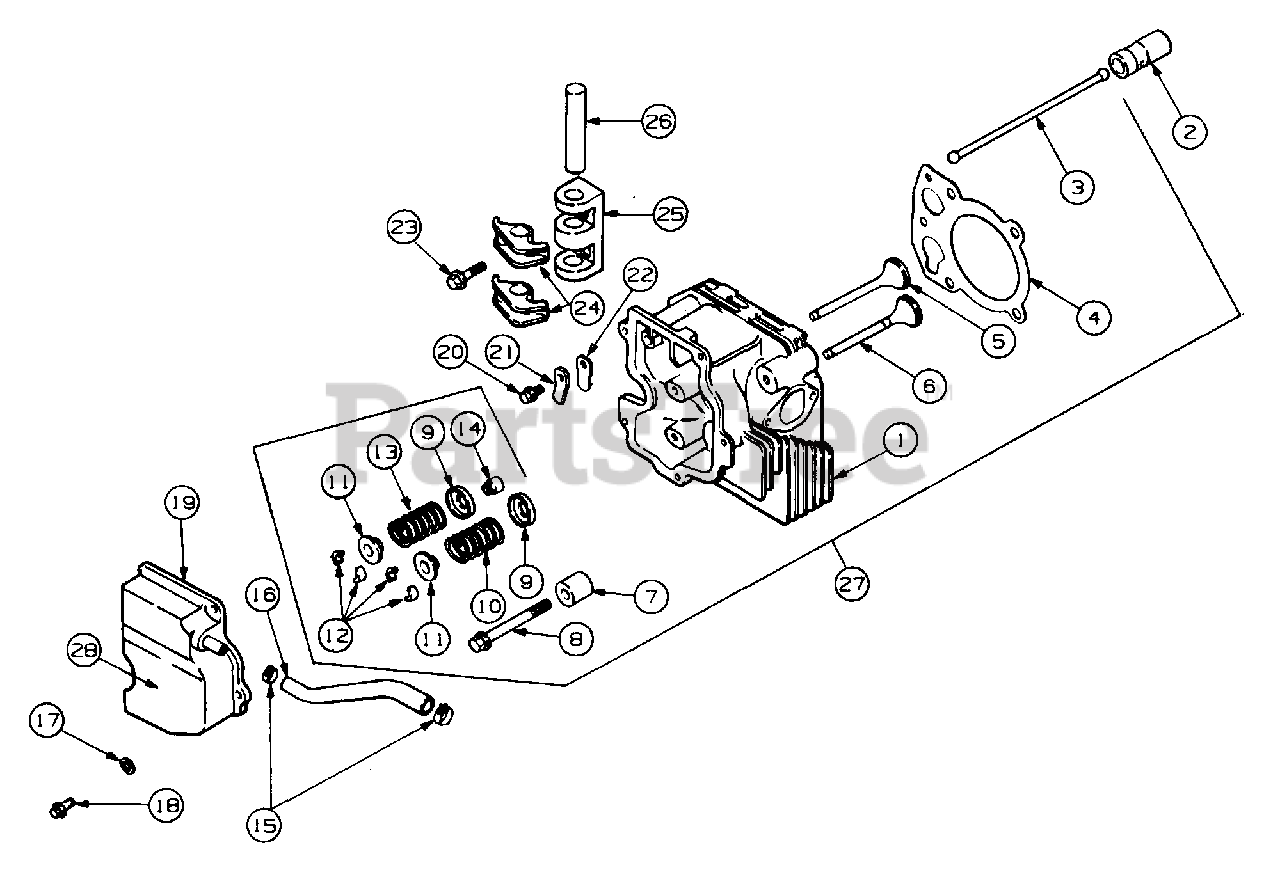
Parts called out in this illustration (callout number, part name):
1	Cylinder Head
2	Lift, Valve
3	Rod, Push
4	Gasket, Cylinder Head
5	Valve, Intake (Std)
6	Valve Exhaust (Std)
7	Spacer, Head Bolt Exhaust Port
8	Screw, Cyl Head, M10 X 1.5 X 81
9	Retainer, Spring
10	Spring, Exhaust Valve
11	Cap, Valve Spring
12	Kit, Retainer
13	Spring, Intake Valve
14	Seal, Valve Stem
15	Clamp, Hose
16	Hose, Breather
18	Screw, Valve Cover, M6 X 1.0 X 20
19	Cover, Valve w/Nipple
20	Screw, Breather Reed Ret, M5 X 0.8 X 10
21	Retainer, Breather Reed
22	Reed, Breather
23	Screw, Rocker Bridge, M6 X 1.0 X 25
25	Bridge, Rocker Arm
26	Shaft, Rocker Arm
27	Kit, Cylinder Head (Includes Ref No. 1, 3 thru 14 & 23 thru 26)
28	Graphic, OHV Engine
